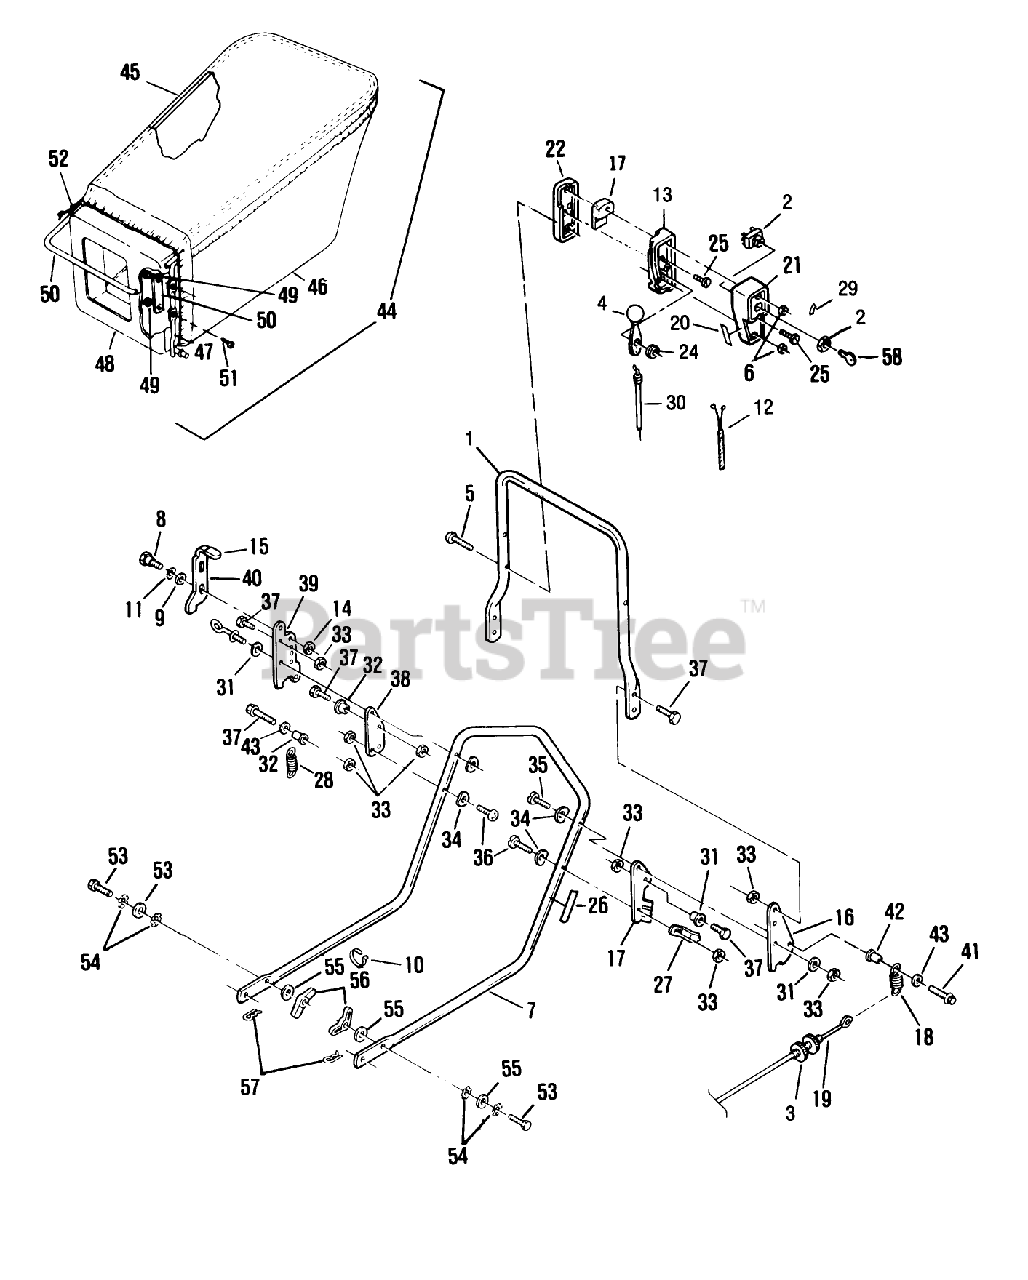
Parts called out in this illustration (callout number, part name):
4	LEVER&KNOB AY WES
5	SCREW
6	NUT C/LOCK E
8	BOLT RB&W
9	WASHER M
14	LOCKNUT E
15	KNOB (S&R)
18	SPRING
19	CABLE AY
24	WASHER-SPRING
25	SCREW
29	Decal-Start
30	T/CABLE WESCON
33	NUT-LOCK F
34	WASHER-CURVED
35	SCREW LARSON
42	SPACER ROCKFORD
43	WASHER
45	HANGER BAG TROX
48	BAG ADAPTOR PL
49	LOCKNUT E
55	WASHER
56	NUT-WING
